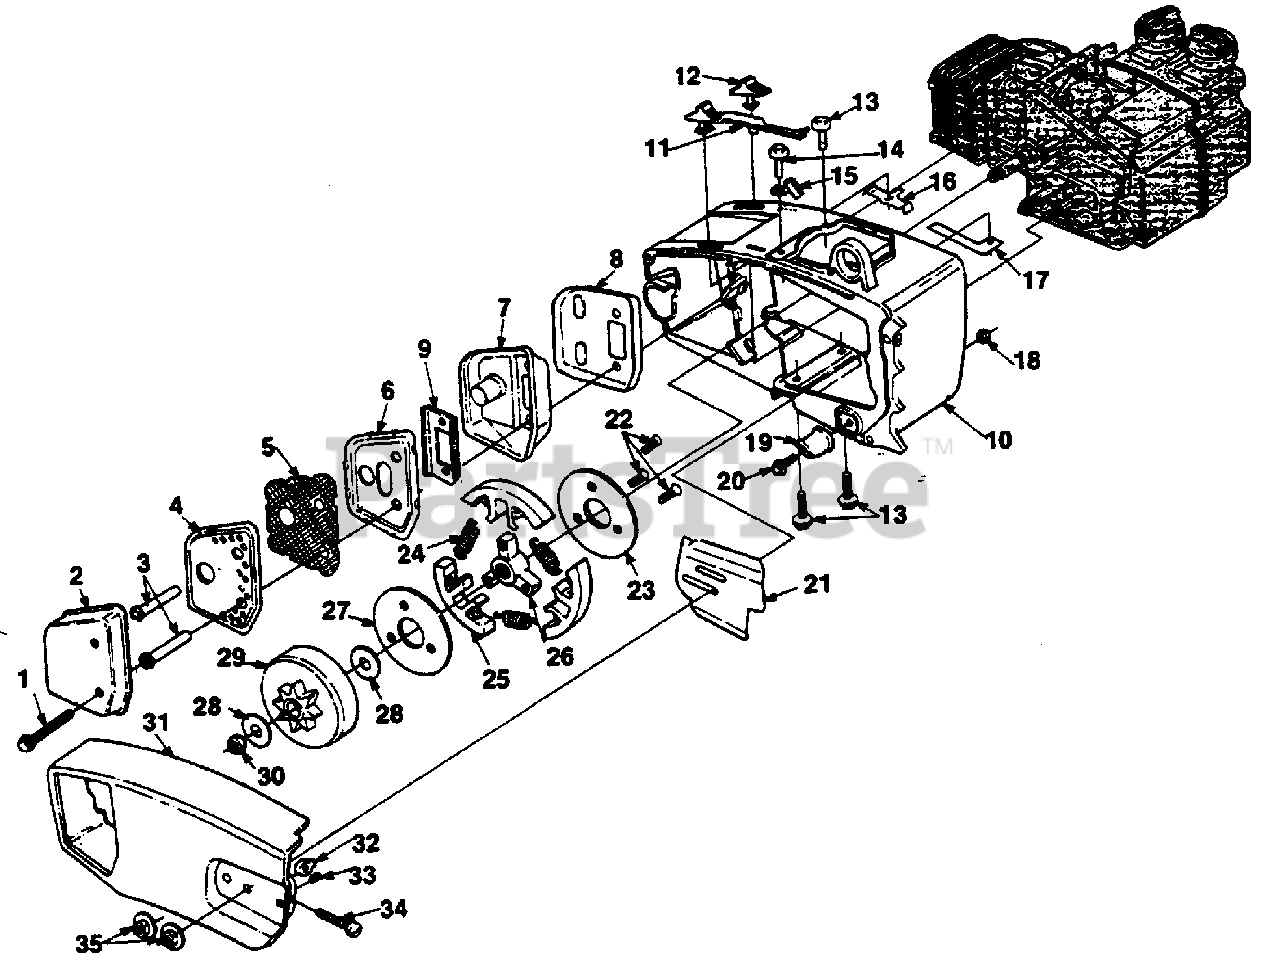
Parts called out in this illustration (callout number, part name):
2	CAP- Muffler
4	BAFFLE- Muffler
5	SCREEN- Spark arrestor
6	BAFFLE- Muffler
7	BODY- Muffler
8	DEFLECTOR- Exhaust
9	PLATE- Muffler
10	HOUSING- Engine
11	BUTTON- Choke
12	BUTTON- Stop switch
13	SCREW- Hex Sems 10-24 x 5/8
14	SCREW- 10-24 x .625
15	BRACKET- Cable
16	SPRING- Stop switch
17	CONTACT- Stop switch
18	NUT- Lock 10-24
19	STOP- Chain
20	SCREW- Mach hex 10-24 x 5/8
21	PLATE- Guide bar
22	SCREW- Flat hd. 7/16-18
23	COVER- Clutch (outer)
24	SPRING- Ext.
25	SHOE- Clutch
26	SPIDER- Clutch
27	COVER- Clutch (inner)
28	WASHER- Thrust
29	SPROCKET & DRUM (37/375 chain only) 6T
30	NUT- Lock 5/16-24
31	COVER- Drivecase
32	PIN- Guide bar adjusting
33	"E" RING
34	SCREW- Guide bar adjusting
35	NUT- Flange 1/4-20
